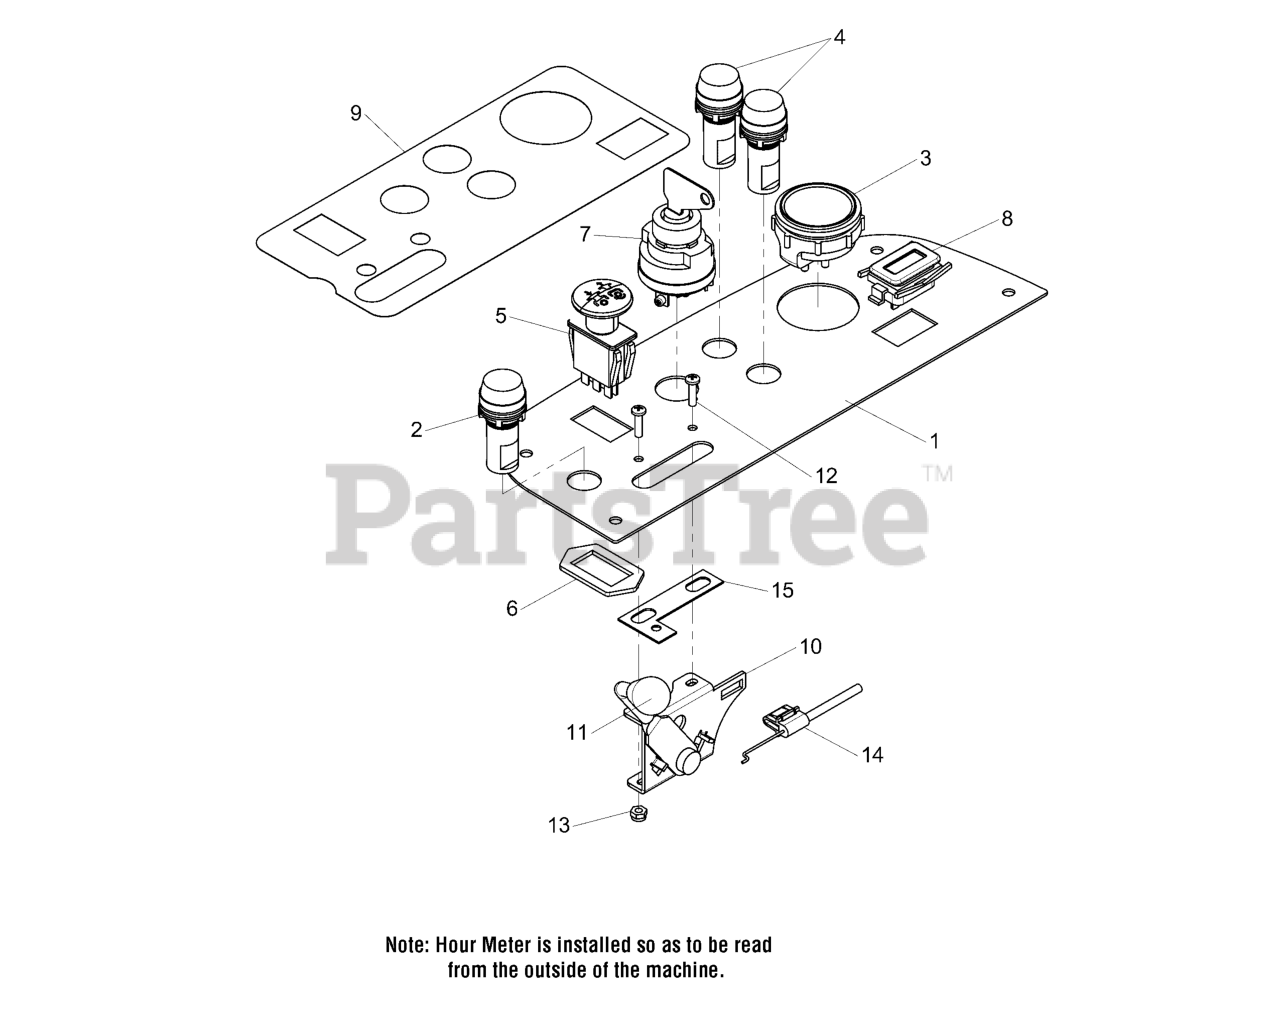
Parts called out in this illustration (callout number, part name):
1	PANEL, CONTROL - RH
2	LIGHT, GLOW PLUG, 22MM AMBER
3	GAUGE, WATER TEMPERATURE
4	LIGHT, WARNING, 22MM RED
5	SWITCH, BLADE ENGAGEMENT
6	RING, SWITCH RETAINER
7	SWITCH, Ignition, Complete
8	HOUR METER
9	DECAL, CONTROL PANEL, DIESEL
10	HANDLE, THROTTLE CONTROL
11	THROTTLE CONTROL HANDLE/KNOB
12	SCREW, #10-24 X 1/2" ROUND PHILLIPS
13	NUT, #10-24 HEX NYLON LOCK
14	CABLE, THROTTLE CONTROL, 47.5"
15	PLATE, THROTTLE STOP
